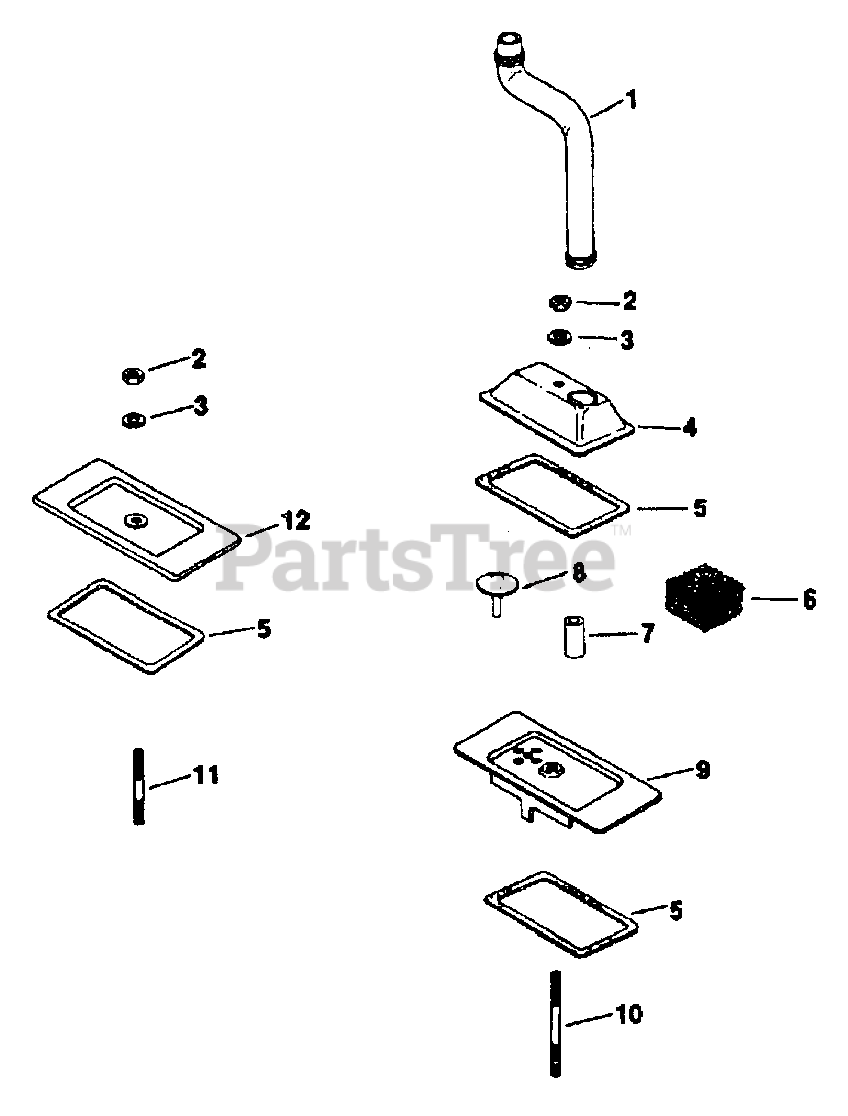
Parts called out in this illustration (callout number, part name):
1	HOSE, BREATHER
2	NUT
3	WASHER
4	COVER
5	GASKET, COVER
6	FILTER, BREATHER
7	SEAL, BREATHER
8	VALVE, BREATHER
9	COVER
10	STUD
11	STUD
12	COVER
